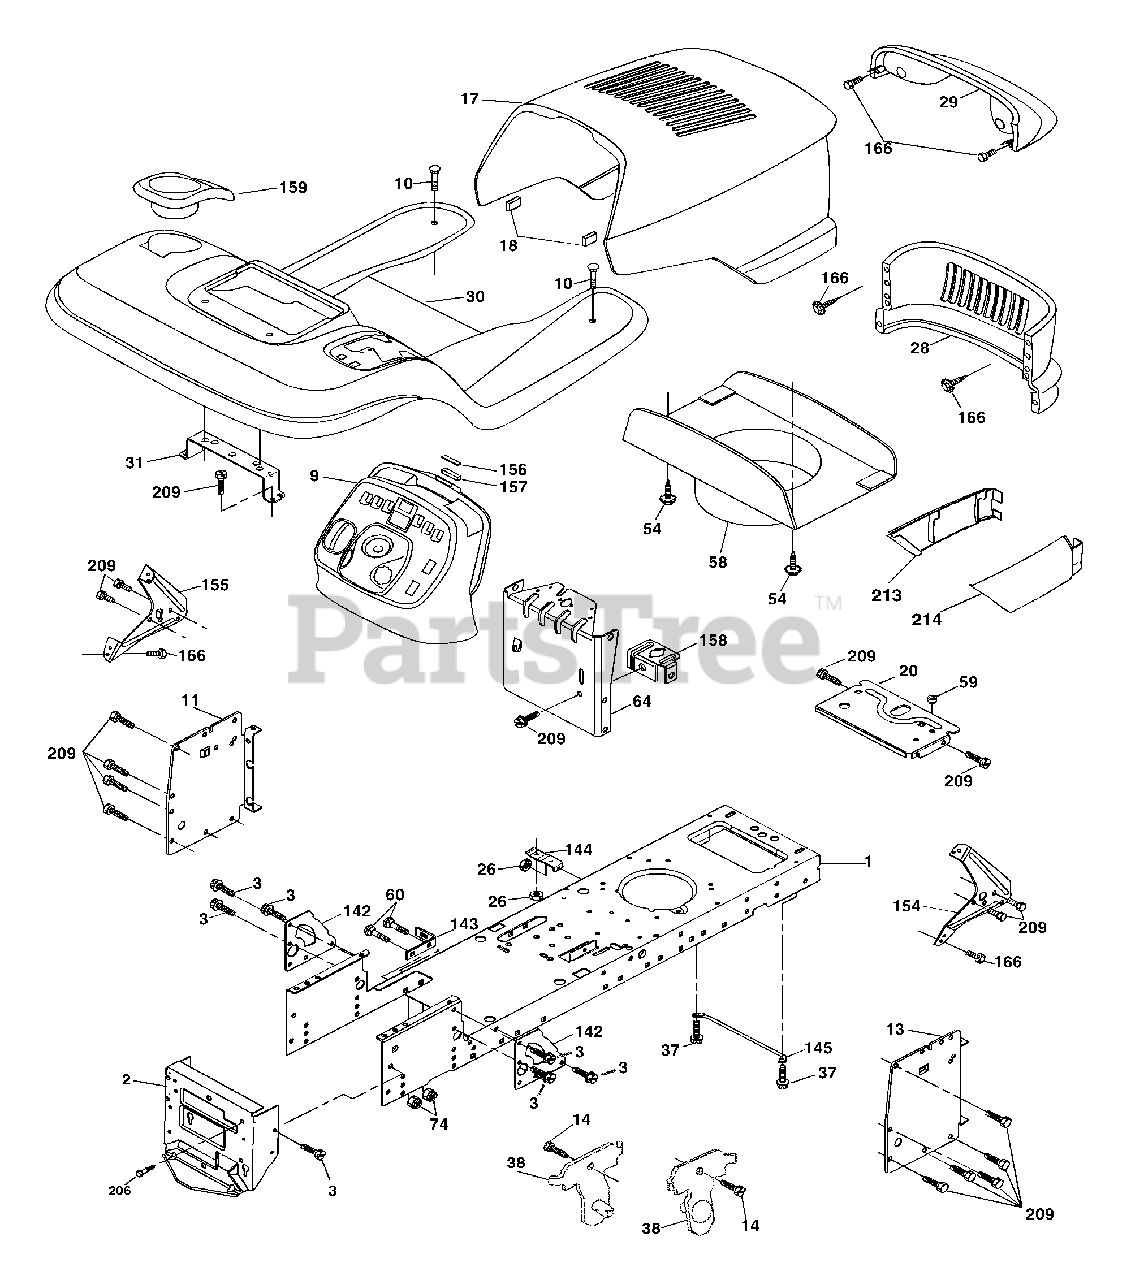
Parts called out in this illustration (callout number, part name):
1	Chassis
2	Drawbar
3	Screw 3/8-16 x 3/4
9	Dash
10	Bolt 3/8-16 x 1
11	Panel Dash Lh
13	Panel Dash Rh
14	Screw Thdrol 3/8-16 x 1/2
17	Hood
18	Hood Bumper
20	Plate Battery
26	Nut Lock Hex W/Ins 3/8-16 Unc
28	Grille
29	Light Asm. Bar
31	Bracket Fender
37	Screw Thdrol 6/16-18 x 1/2 TYT
38	Bracket, Asm. Pivot Mower Rear
54	Screw Hex Wshd 8-18 x 7/8
58	Duct Hood
59	Bushing Snap
60	Bolt Rd Hd Sqnk 3/8-16 Unc x 3/4
64	Dash Lower
74	Nut Crownlock 3/8-16 Unc
142	Plate Reinforcement STLT
143	Bracket Swaybar Chassis
144	Bracket Footrest
145	Rod Pivot Chassis/Hood
154	Bracket Dash Rh
155	Bracket Dash Lh
156	Striker Plate
157	Magnet Stealth
158	Bracket Parking Brake
159	Cupholder
166	Screw Hw Hd Hi-Lo #13-16 x 3/4
206	Bolt Shoulder 5/16-18
209	Screw Hexwsh Thdrol 3/8-16 x 3/4
213	Skirt Grille LH
214	Skirt Grille RH
